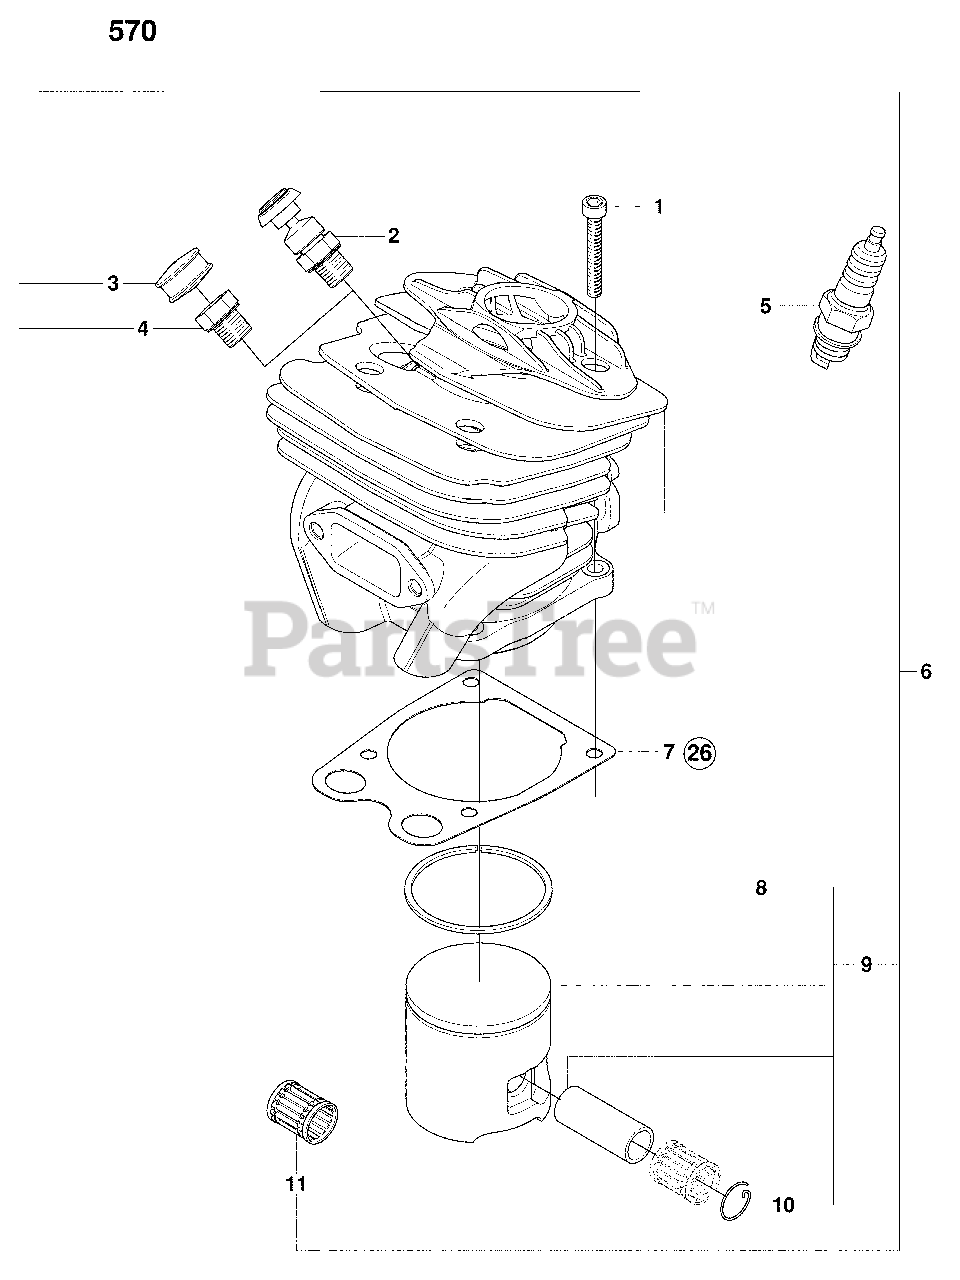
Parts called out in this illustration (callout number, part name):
1	Screw, MC6S 5 X 25
2	Valve
4	Cylinder Plug
5	Solid Spark Plug, BPMR7A
6	Cylinder
8	Piston Ring
9	Piston, 49mm
11	Needle Bearing Piston Pin, 12 X 1
26	Gasket Set
